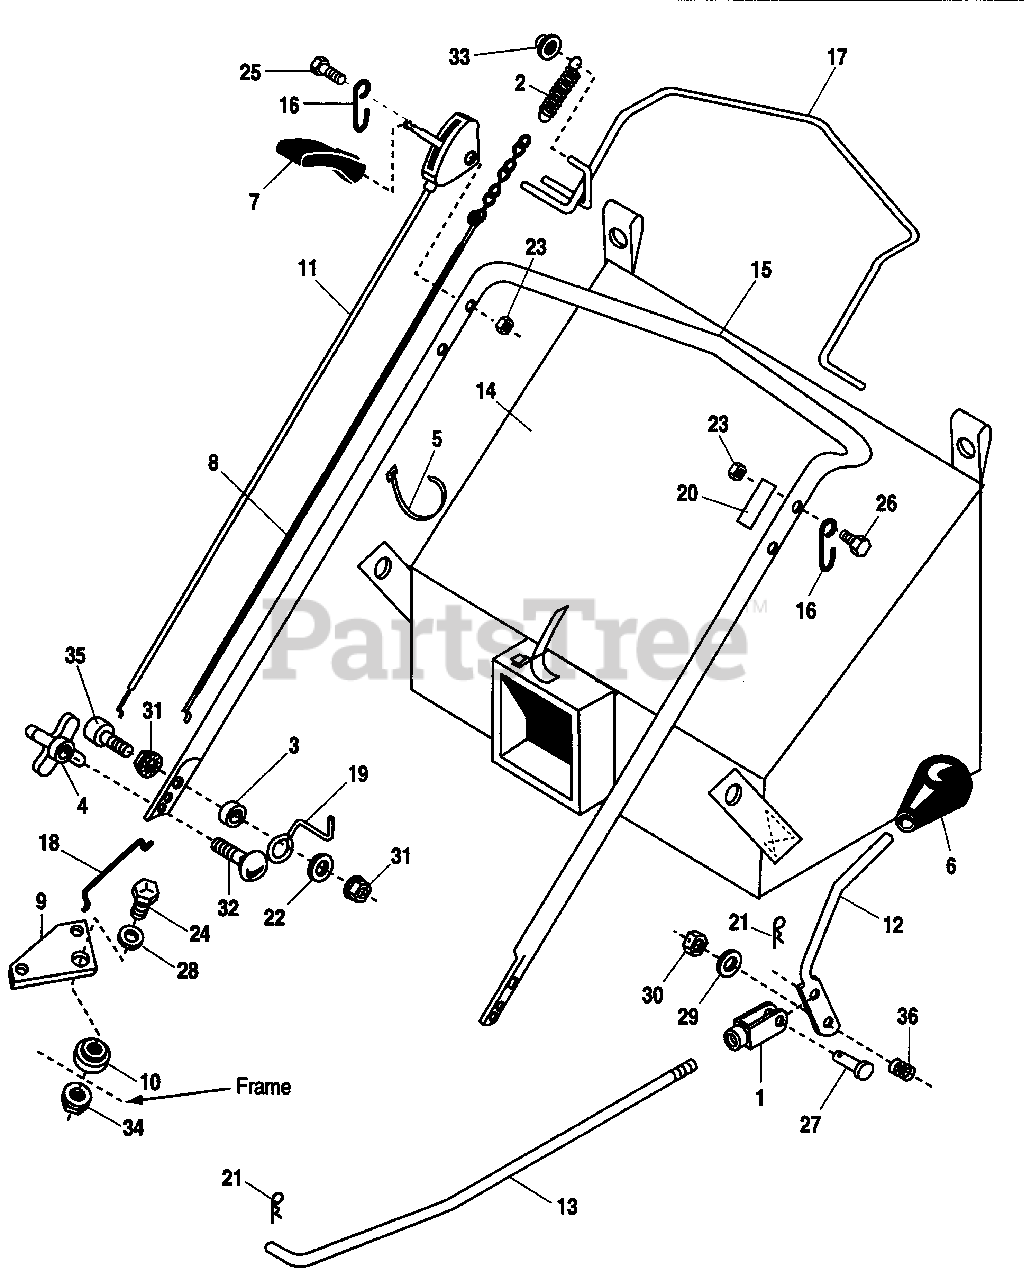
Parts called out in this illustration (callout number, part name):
4	KNOB, Handle
5	TIE, Self-locking
6	KNOB, Handle, Height Adjustment
7	HANDLE, Shift Control
8	CABLE, Traction
10	SPACER, Pivot
11	CABLE, Shift Control
12	HANDLE, Height Adjustment
18	LINK, Traction
19	GUIDE, Cable
20	DECAL, Clutch Bail
21	PIN, Quick
22	WASHER, 5/16
23	NUT, Hex, Nylock 1/4-20
24	CAPSCREW, Hex Hd., 5/16-18 x 1
25	CAPSCREW, Hex Hd., 1/4-20 x 2
26	CAPSCREW, Hex Hd., 1/4-20 x 1-1/2
28	WASHER, 5/16
29	WASHER, 3/8
30	NUT, Center Lock, 3/8-16
31	NUT, Serrated, Flange, 5/16-18
32	CARRIAGE BOLT, 5/16-18 x 3/4
33	PUSH NUT, Pal, 5/16
34	NUT, Hex, Flange Lock, 5/16-18
35	CAPSCREW, Hex, Socket Hd., 5/16-18 x 1-3/4
